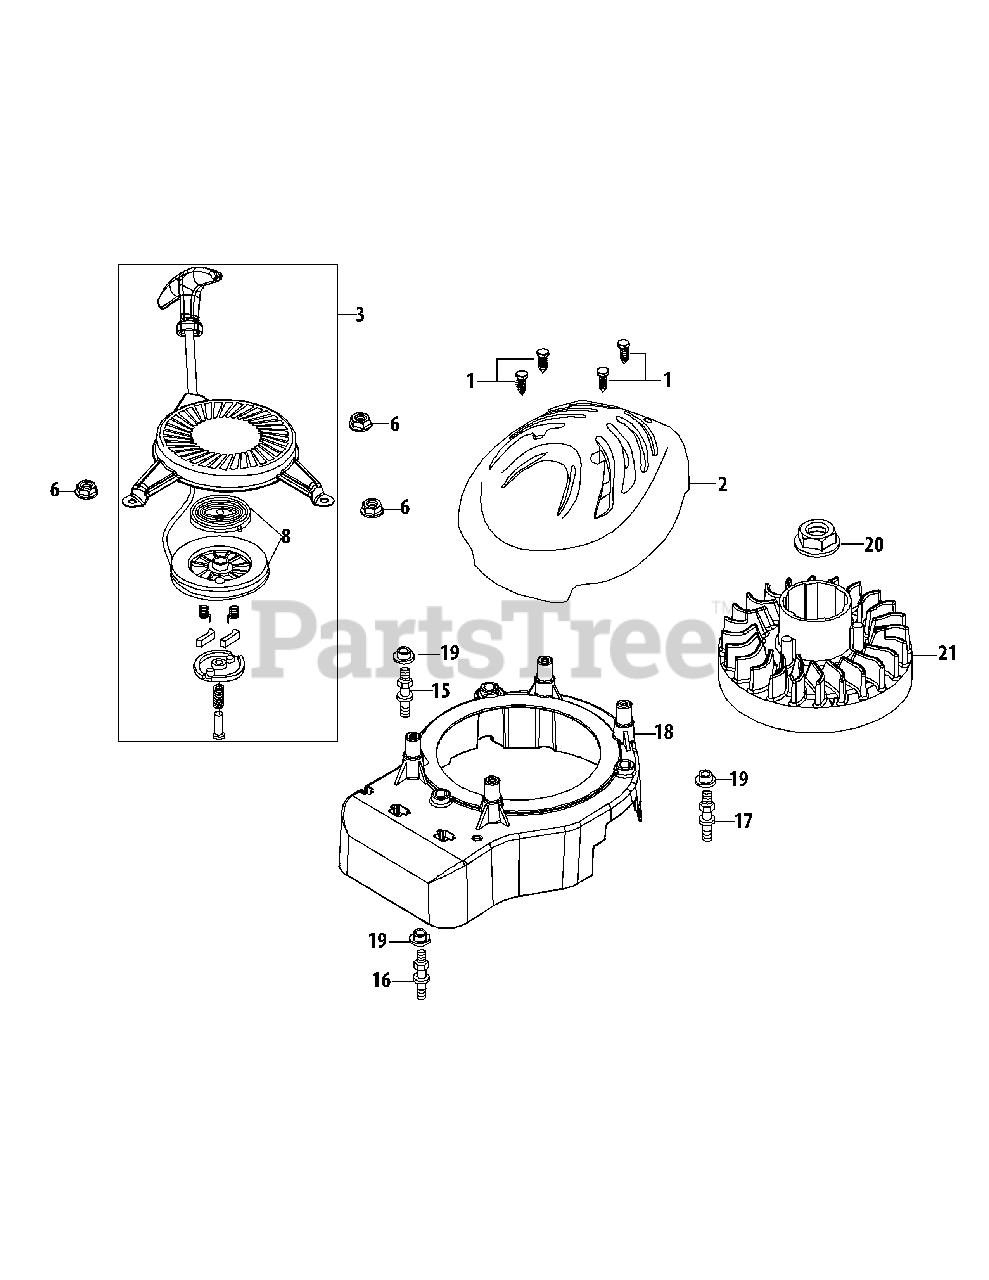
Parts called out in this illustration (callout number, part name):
1	Screw, #12-16 X 1.00"
2	Outer Shroud (Model Specific)
3	Recoil Starter Assembly
6	Nut M6 X 10 Mm
8	Recoil Spring and Pulley Ass'y
15	Stud Left/Black/Ye Zinc
16	Stud Front/Unmarked/Ye Zinc
17	Stud Right/White/Ye Zinc
18	Inner Shroud
19	Engine Shroud Spacer
20	Flywheel Nut M14
21	Flywheel
